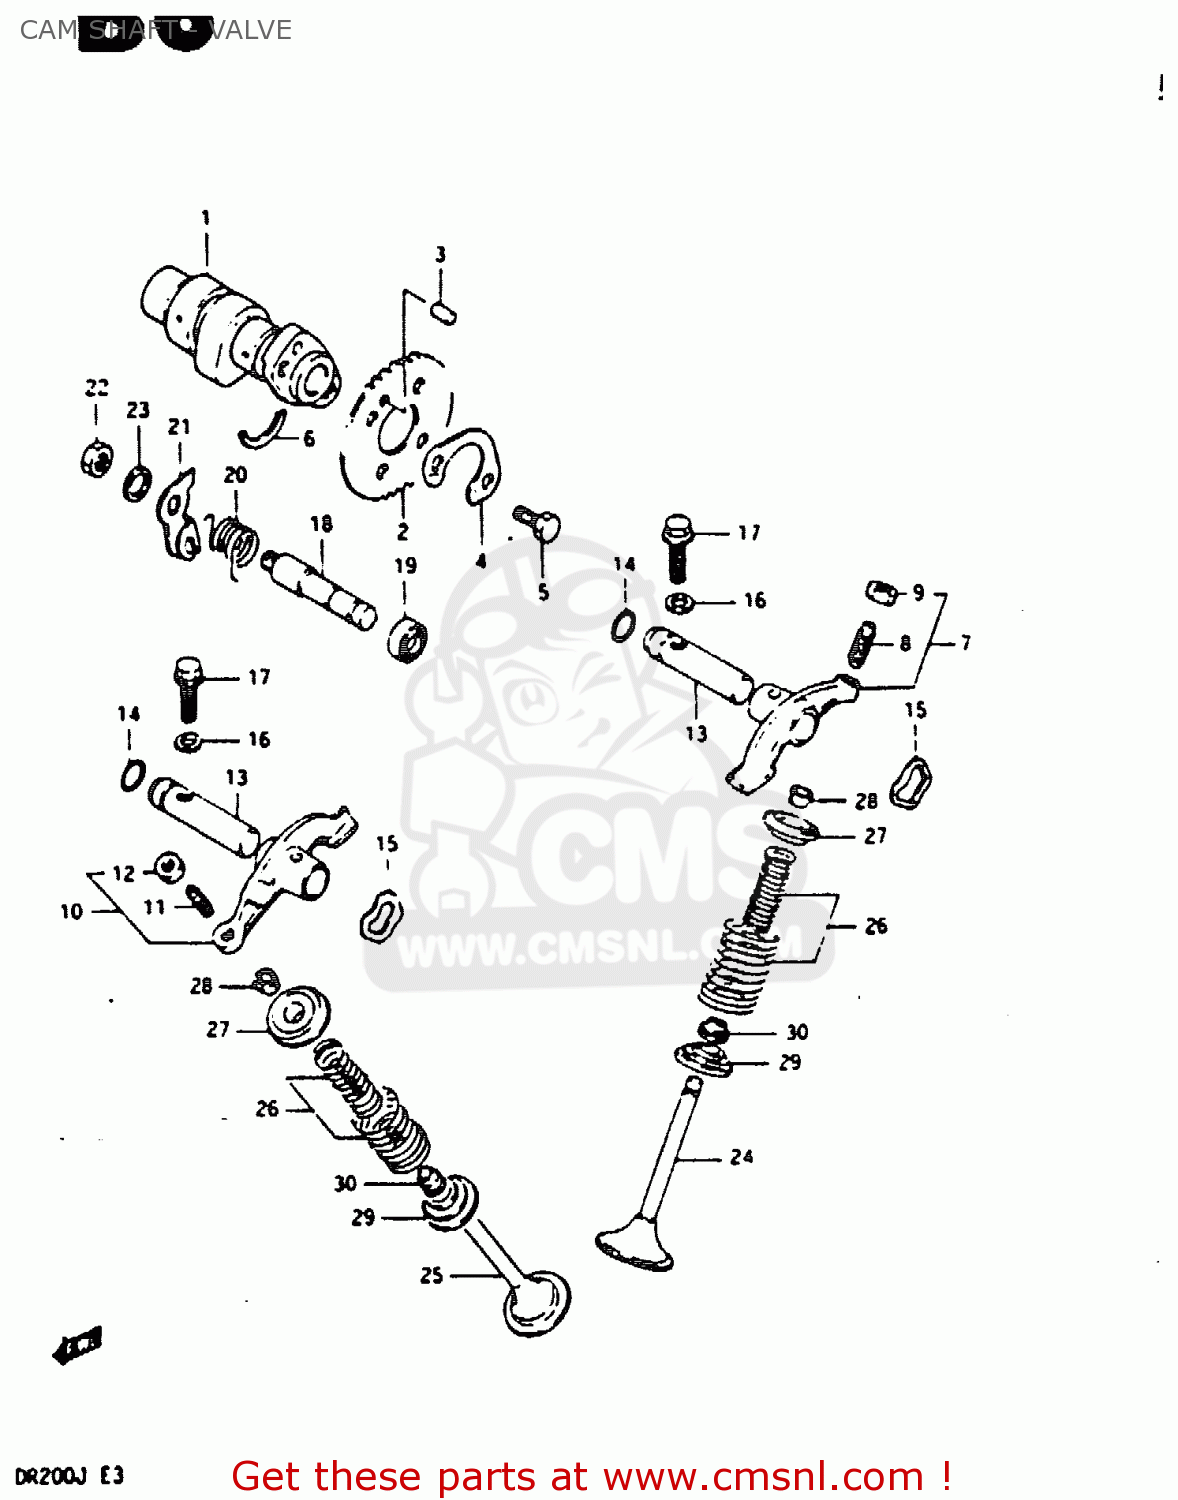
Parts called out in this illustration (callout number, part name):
1	CAMSHAFT
2	SPROCKET,CAMSHAFT
3	PIN(5X8)
4	WASHER,SPROCKET
5	BOLT(6X10.5)
6	C RING
7	ARM,VALVE ROCKER
8	SCREW,TAPPET ADJUSTING
9	NUT,ADJUSTING SCREW
10	ARM,VALVE ROCKER,EXHAUST
11	SCREW,TAPPET ADJUSTING
12	NUT,ADJUSTING SCREW
13	SHAFT,VALVE ROCKET
14	O RING(D:1.9,ID:8.6)
15	WASHER
16	WASHER
17	BOLT
18	SHAFT,DECOMPRESSION
19	OIL SEAL
20	SPRING
21	LEVER,DECOMPRESSION SHAFT
22	NUT 8MM
23	WASHER
24	VALVE,INTAKE
25	VALVE,EXHAUST
26	SPRING SET,VALVE
27	RETAINER,VALVE SPRING
28	COTTER,VALVE
29	SEAT,VALVE SPRING
30	OIL SEAL
